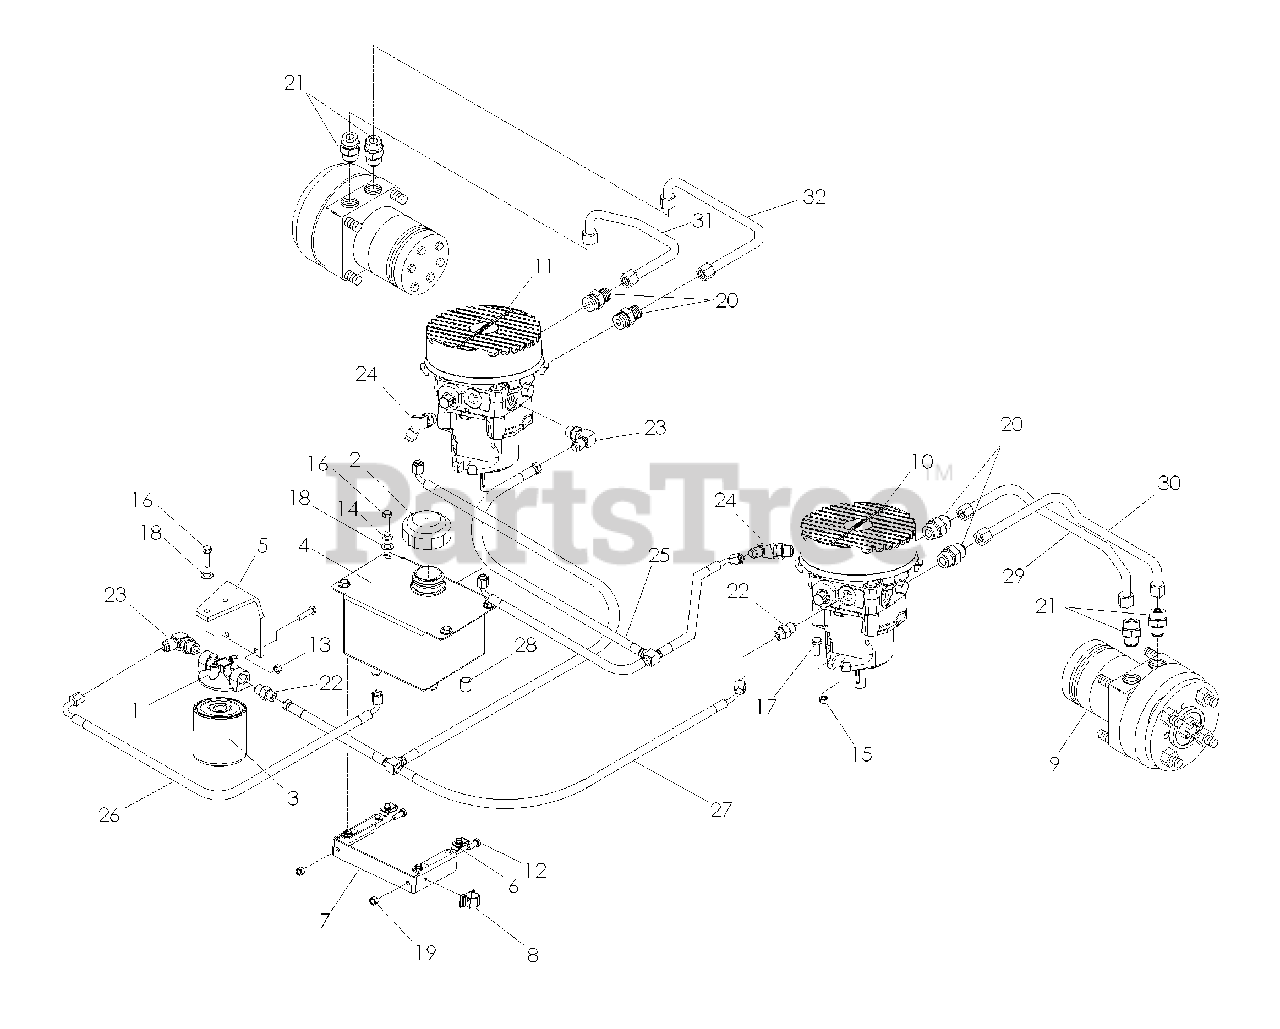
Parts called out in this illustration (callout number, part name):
1	FILTER HEAD
2	CAP HYDRO TANK
5	FILTER BRACKET
6	RETAINER 1/4-20 U-TYPE
7	TANK MOUNT
8	WIRE CLIP PUSH-MOUNT
9	TI15 WHEEL MOTOR
10	PUMP 10cc W/FAN LEFT
11	PUMP 10cc W/FAN RIGHT
12	HCS 5/16-18 x 3/4
13	NUT 1/4-20 HEX NYLOC
14	WASHER, 1/4 SPLIT LOCK
15	NUT 3/8-16 HEX CTR LK
16	HCS 1/4-20 x 3/4
17	HCS 3/8-16 x 1 WHIZLK
18	WASHER 1/4 FLAT
19	NUT 5/16-18 HEX NYLOC
20	FITTING STRAIGHT
21	FITTING STRAIGHT
22	FITTING STRAIGHT
23	FITTING ELBOW
24	FITTING ELBOW
25	"T" ASSEM RETURN
26	TANK HOSE
27	"T" ASSEM SUPPLY
29	HYDRAULIC LINE
30	HYDRAULIC LINE
31	HYDRAULIC LINE
32	HYDRAULIC LINE
